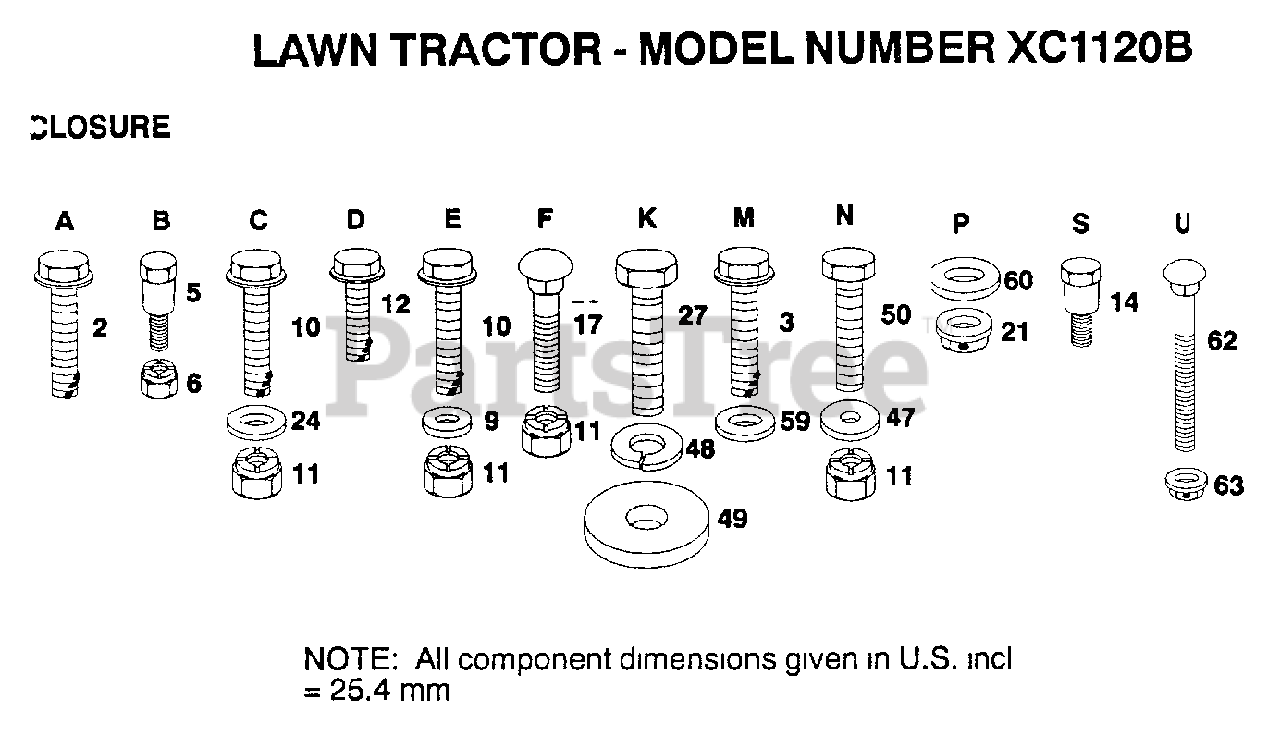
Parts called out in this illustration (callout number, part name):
2	SCREW
3	SCREW GTV
9	WASHER
12	SCREW LT
14	"BOLT,SHOULDER"
17	BOLT
21	PAL NUT LT
24	WASHER
27	BOLT
47	WASHER
48	LOCKWASHER
49	WASHER
50	BOLT
59	WASHER
60	WASHER PM
62	BOLT
